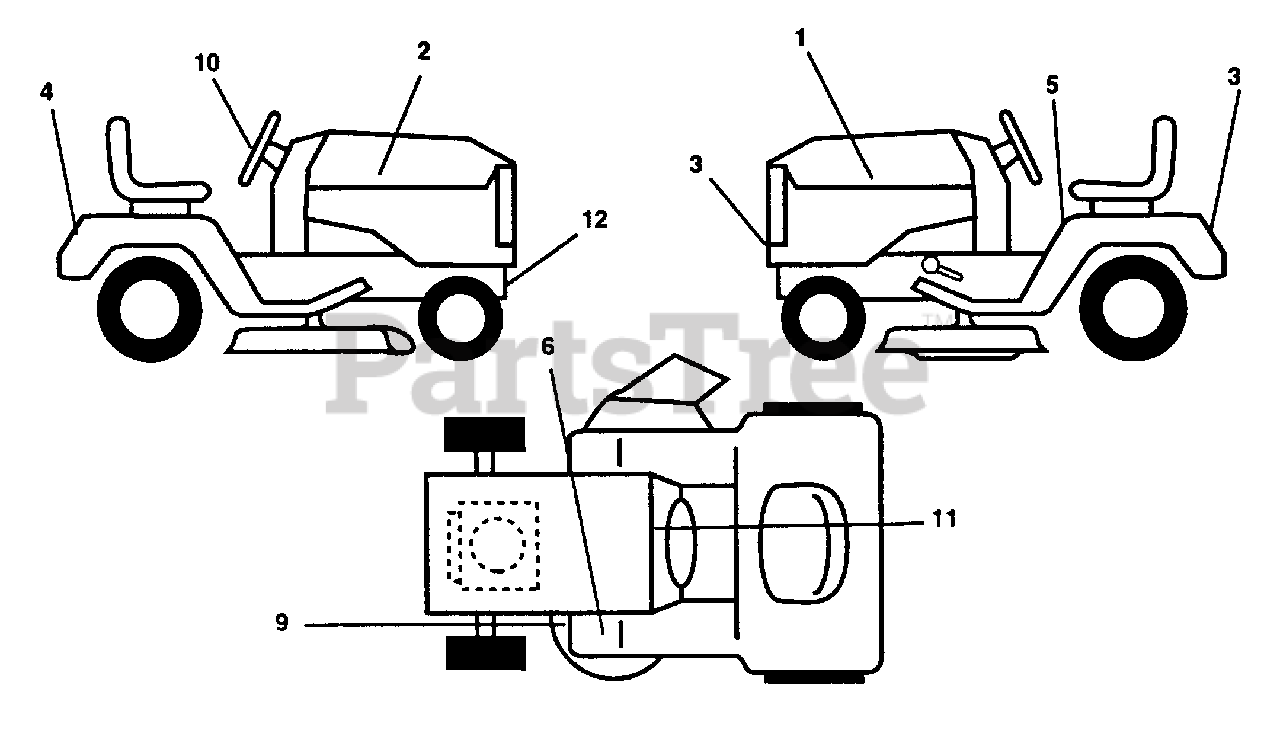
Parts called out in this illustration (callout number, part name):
1	Decal, Hood Stripe, L.H.
2	Decal, Hood Stripe, R.H.
3	Decal, Grill/Fender
4	Decal, Fender (AYP part number)
5	Decal, Caution (AYP part number)
6	Decal, Clutch/Brake (AYP part number)
9	Decal, V-Belt (AYP part number)
10	Decal, Steering Wheel Insert
11	Decal, Instruction/Operating (AYP part number)
12	Decal, Adjust Belt (AYP part number)
